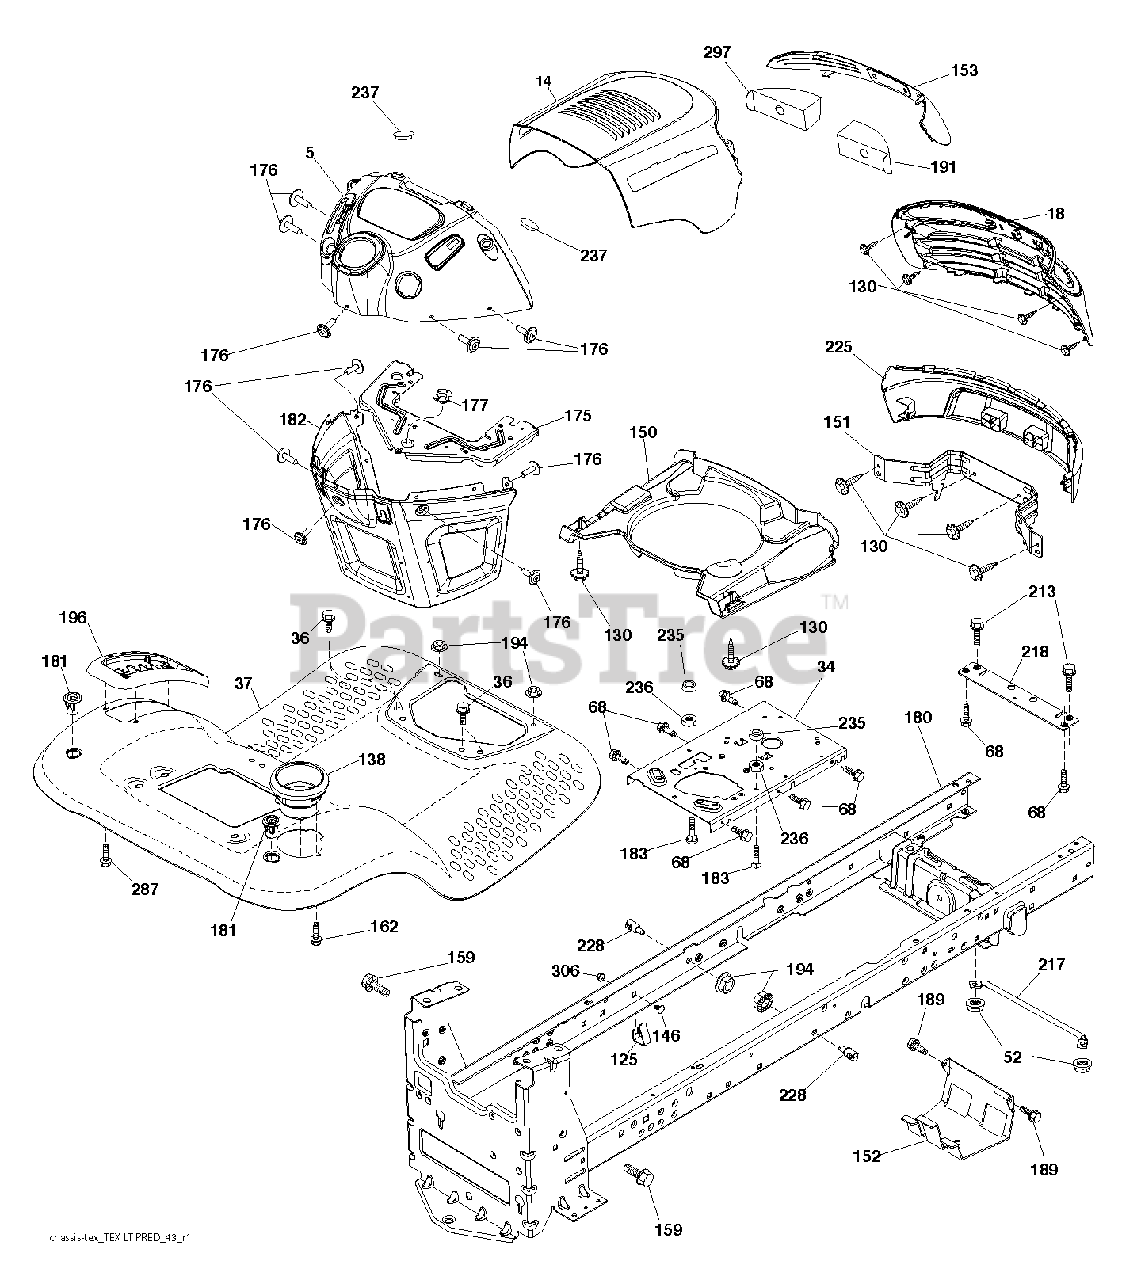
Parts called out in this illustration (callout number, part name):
5	DASH.PRED.LT.CC.ICY.SRVMDR.BLK
37	FENDER.TLT.W/CPH.BLUE
68	SCREW LT
130	SCREW.#10 X 0.750.BOS THREAD
138	CUPHOLDER.TL.TEX.BLACK
150	DUCT.AIR.TOP.VENT.PREDATOR.LT
152	SHIELD BROWNING
153	LENS.PREDATOR.LT
159	SCREW, 3/8-16X3/4
162	SCREW.HI-LO.CONSOLE
176	SCREW.#10-24X5/8.RN.QU
180	CHASSIS
183	BOLT.5/16-18X1-1/4 FULL THD
191	INSERT.REFLECT.PREDATOR.LT.RH
194	NUT LOCK HEX FLANGE 5/16-18
196	CONSOLE.ASM.DECKLFT.BL/RBT.TLT
225	BUMPER.PREDATOR.LT.BLACK
228	STUD.FASTNER.W/ANTI-ROTATE
235	SPACER FENDER
236	NUT.CENTERLOCK.5/16-
297	REFLECTOR.INSERT.PRED.LH.LT
